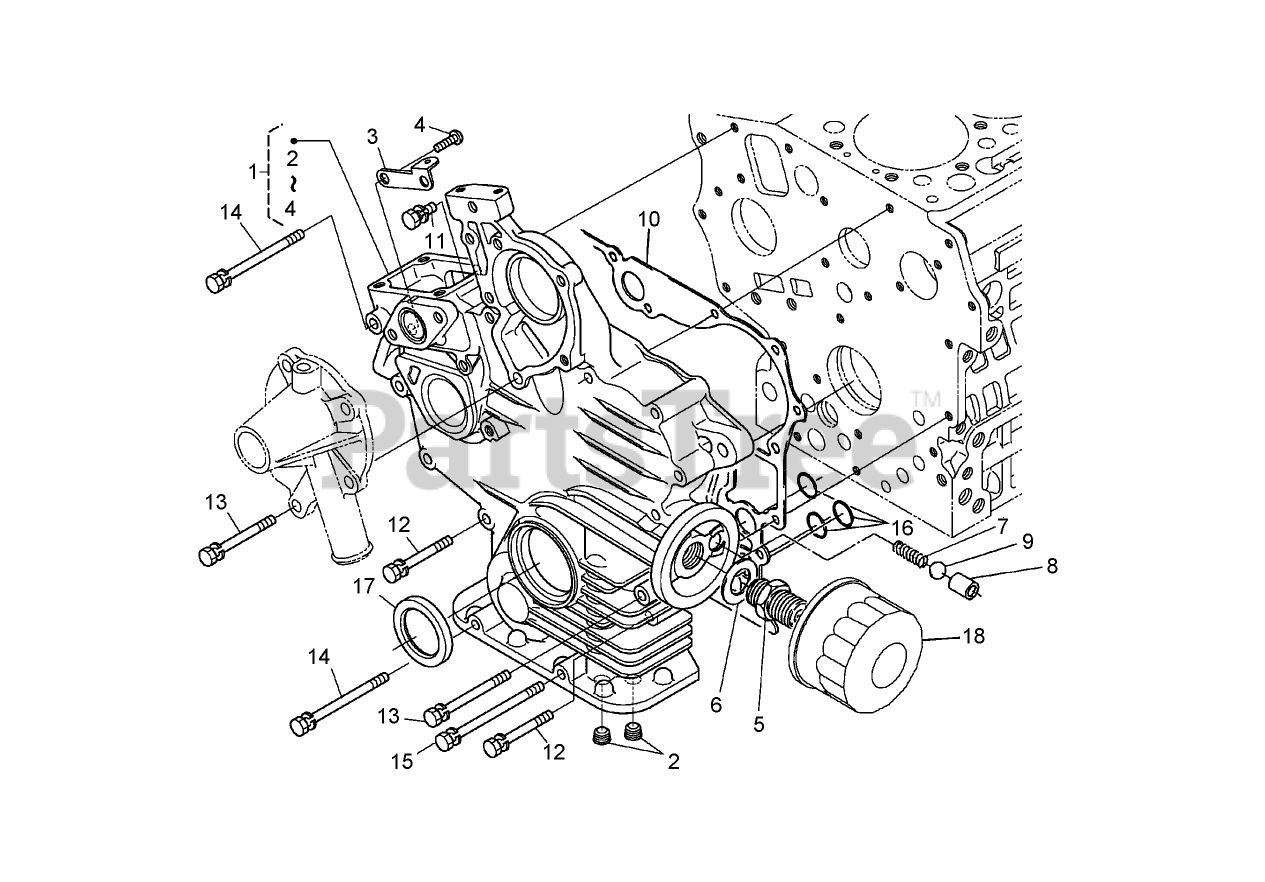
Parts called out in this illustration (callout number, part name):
1	CASE-GEAR
3	STAY-SPRING, START
5	JOINT-PIPE
6	WASHER-PLAIN
7	SPRING
8	SEAT-VALVE
10	GASKET-GEARCASE
12	BOLT
16	O-RING
17	SEAL-OIL
18	CARTRIDGE-FILTER, OIL
